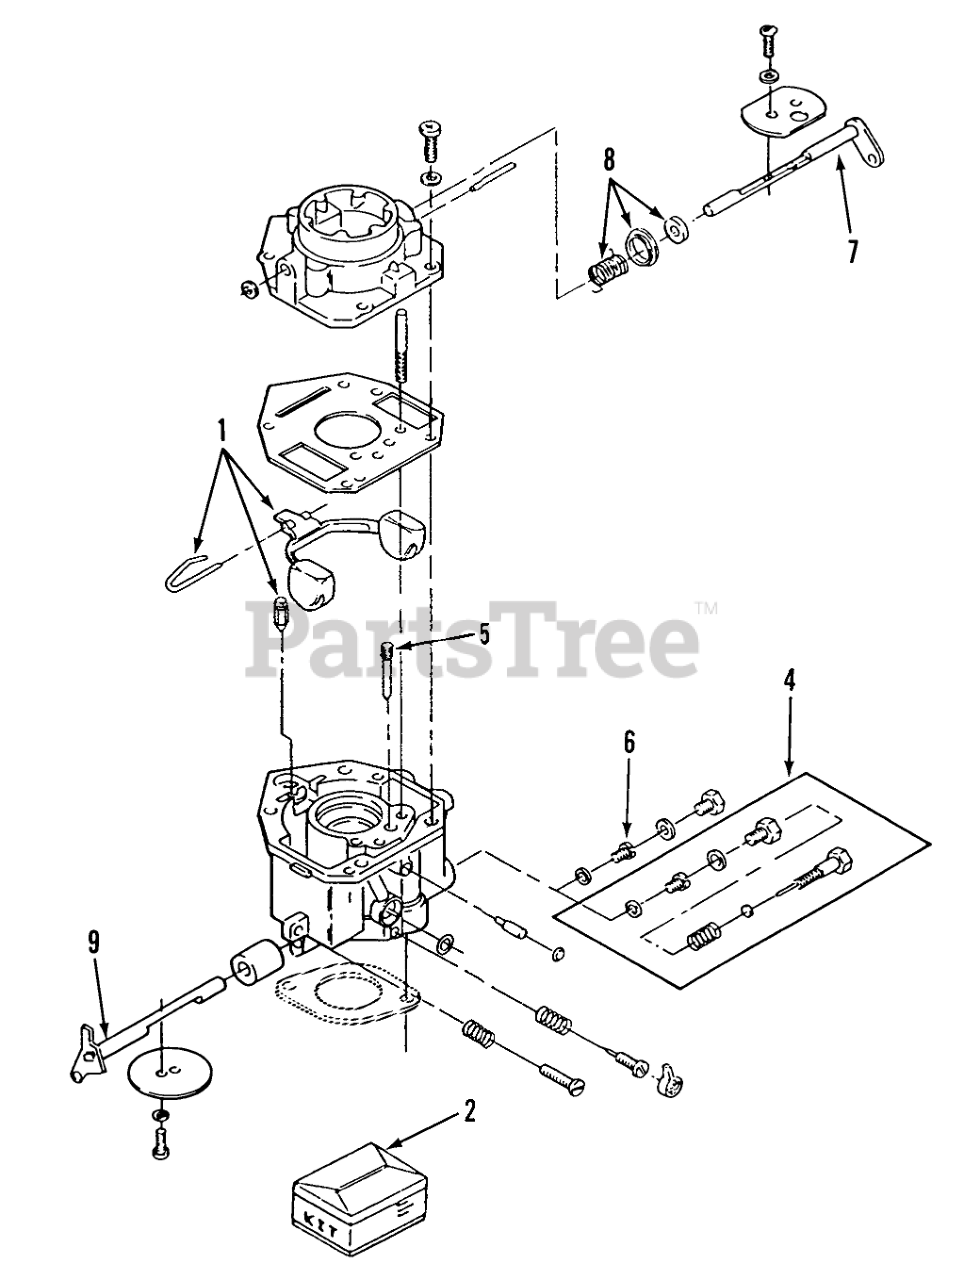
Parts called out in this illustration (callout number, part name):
1	Float Kit (includes Float, Pin and Valve)
2	Repair Kit (includes Screw and Plug package, Gasket package, Float Valve, Idle Adjustment Needle and Spring, Mounting Gaskets, Idle Limit Cap)
4	Variable Jet Kit-Optbnal (High Altitude Application Includes Power Jet and Gasket, Retainer, Power Needle Spring, Power Needle and Power Plug Gasket)
5	Idle Jet
6	POWER JET
6	Power Jet 20HP
7	Choke Shaft-Kit (includes Choke Valve, Valve Set Screw and Air Filter)
8	Choke Lever-Kit (includes Choke lever Ring, Choke Spring and Choke Collar)
9	Throttle Shaft-Kit (includes Valve Set Screw, Air Filter and Throttle Valve)
